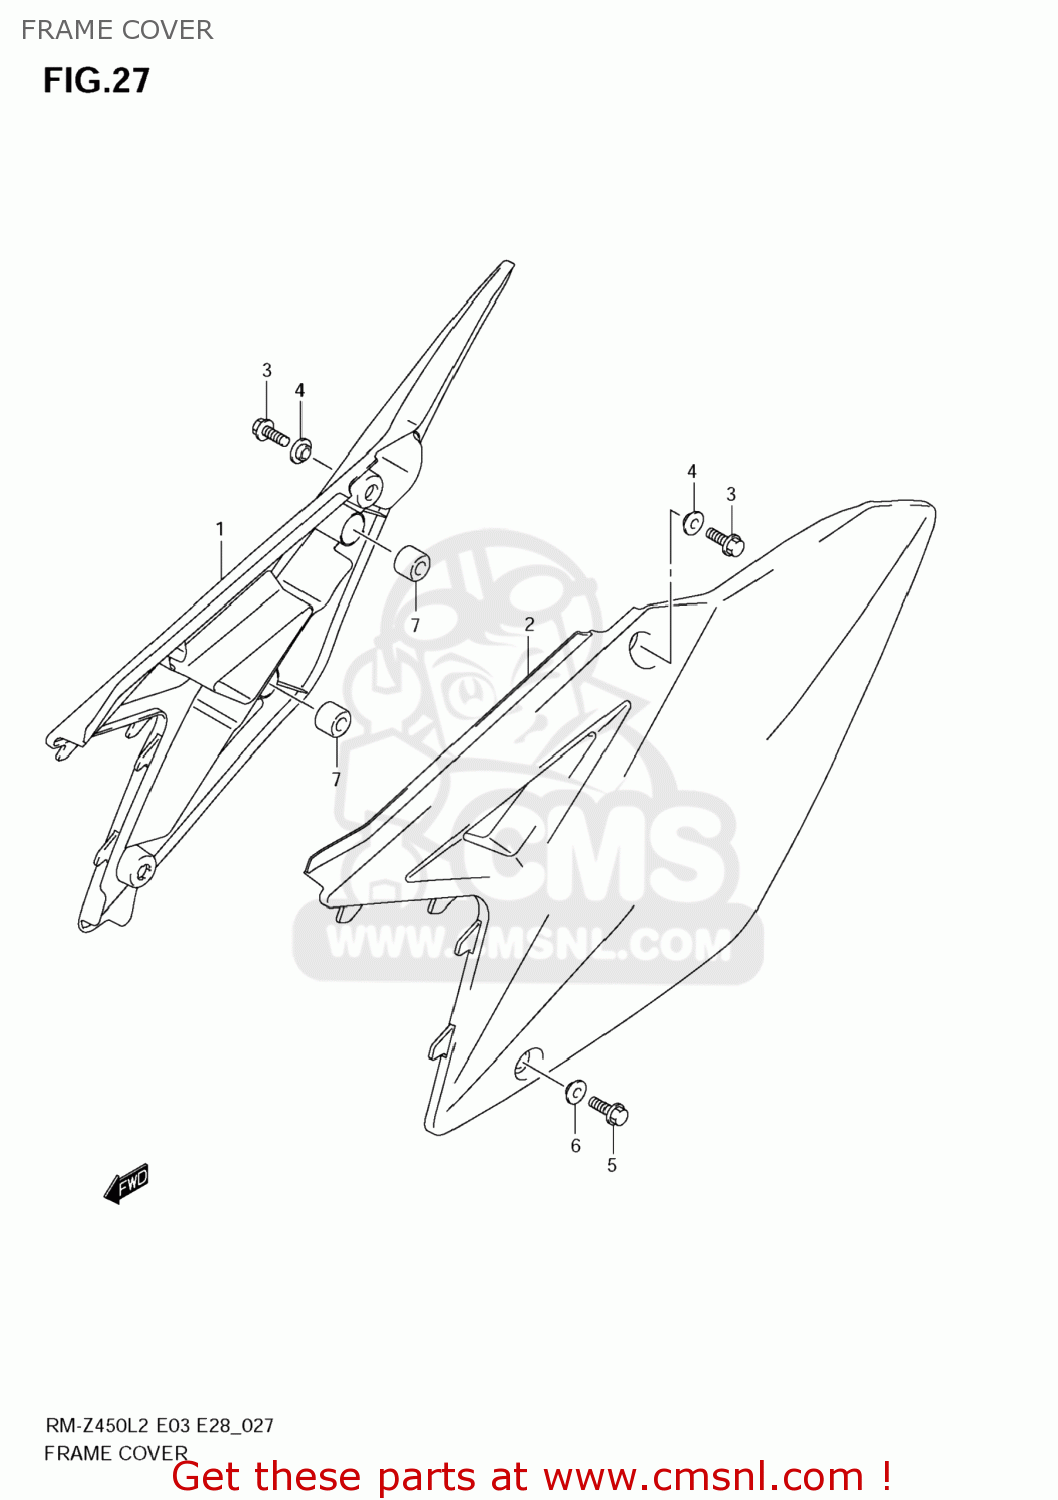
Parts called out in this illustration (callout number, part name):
1	COVER,FRAME,R(WHITE)
2	COVER,FRAME,L(WHITE)
3	BOLT
4	WASHER
5	BOLT
6	WASHER
7	CUSHION
